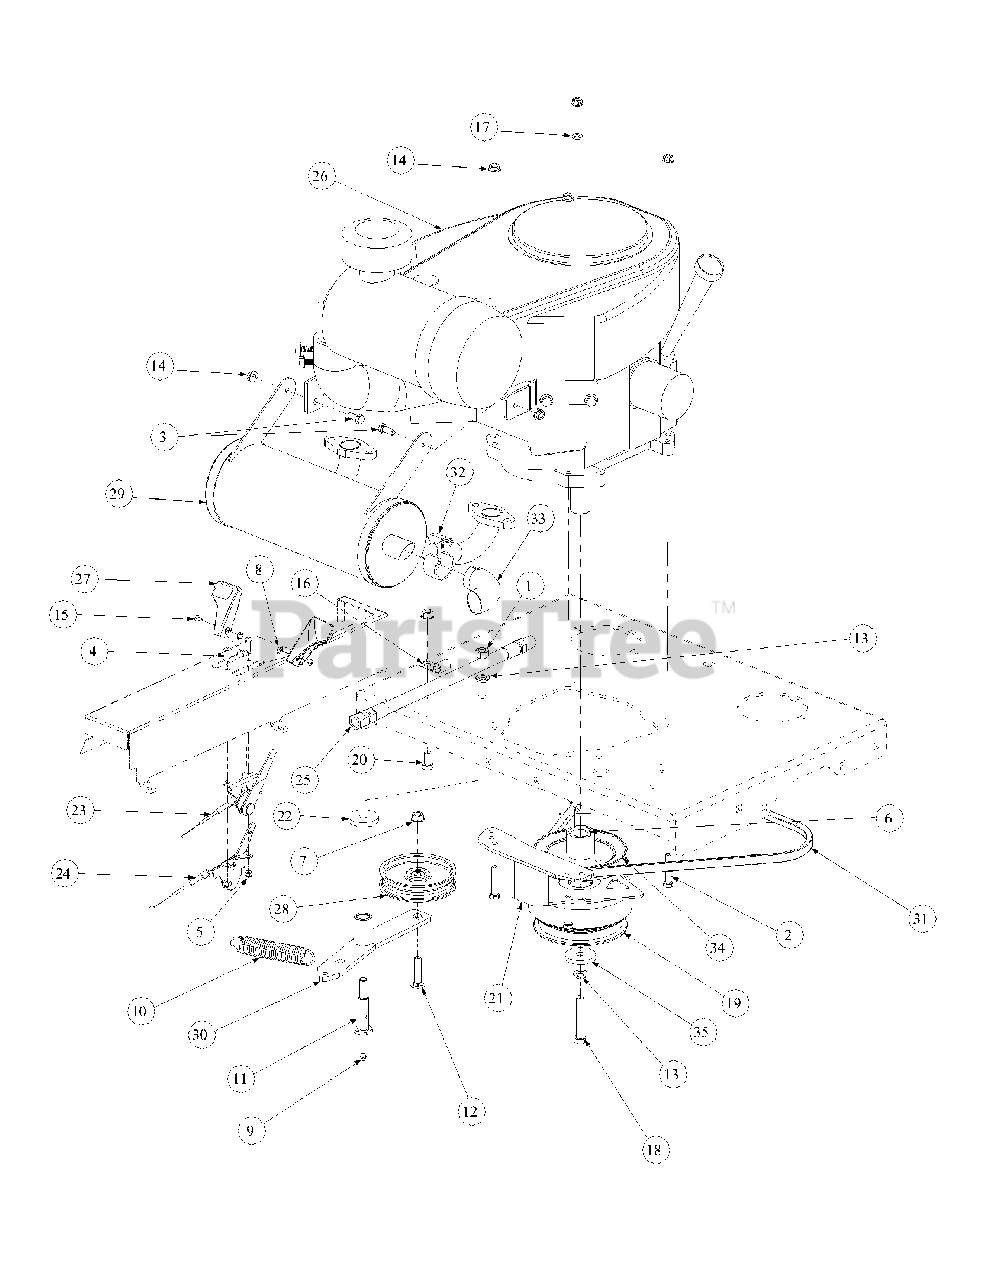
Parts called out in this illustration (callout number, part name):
1	Hex Nut, 7/16-14
2	HHCS, 5/16-18, 1-3/4
3	Hex Cap Screw, 5/16-18 x 3/4
4	Round Hd. Machine Screw, 10-32 x 3/4
5	Lock Nut, Nylon Insert, 10-32
6	Key, 1/4 x 1/4 x 3
7	Flange Lock, Hex Nut, 3/8-16
8	Nut Washer, W/Star, 8-32
9	Grease Fitting, 1/4-28 x 3/16
10	Extension Spring, 1.0 OD x 5.125
11	Shoulder Screw, 7/16-14
12	Hex Carriage Screw, 3/8-16, 1.75
13	Lock Washer, 7/16
14	Hexflange Lock Nut, 5/16-18
15	Machine Screw, 8-32, .375
16	Clip, Heat Shield Cable
17	Flat Washer, 5/16
18	Capscrew, 7/16-20 x 2.50
19	Clutch Brake, 1.125 ID
20	Hex Cap Screw, 3/8-16, .750
21	Retainer Clutch Assembly, Ogura
22	Flat Washer, 7/16 ID x 1.75 OD x .25
23	Choke, Control Cable, 43.0
24	Throttle, Control Cable, 39.0
25	Oil Drain Hose
26	25HP Twin Engine, Kawasaki
27	Control Throttle Knob
28	Flat Pulley with Flanges
29	Muffler Accessory, Kawasaki
30	Engine Idler Arm Assembly includes:
31	V Belt, A Section x .47.3
32	Tube Clamp, 1.375
33	Muffler Accessory Exhaust Tube
34	Pump Drive Pulley
35	Flat Washer, 7/16 ID x 1.75 OD x .25
